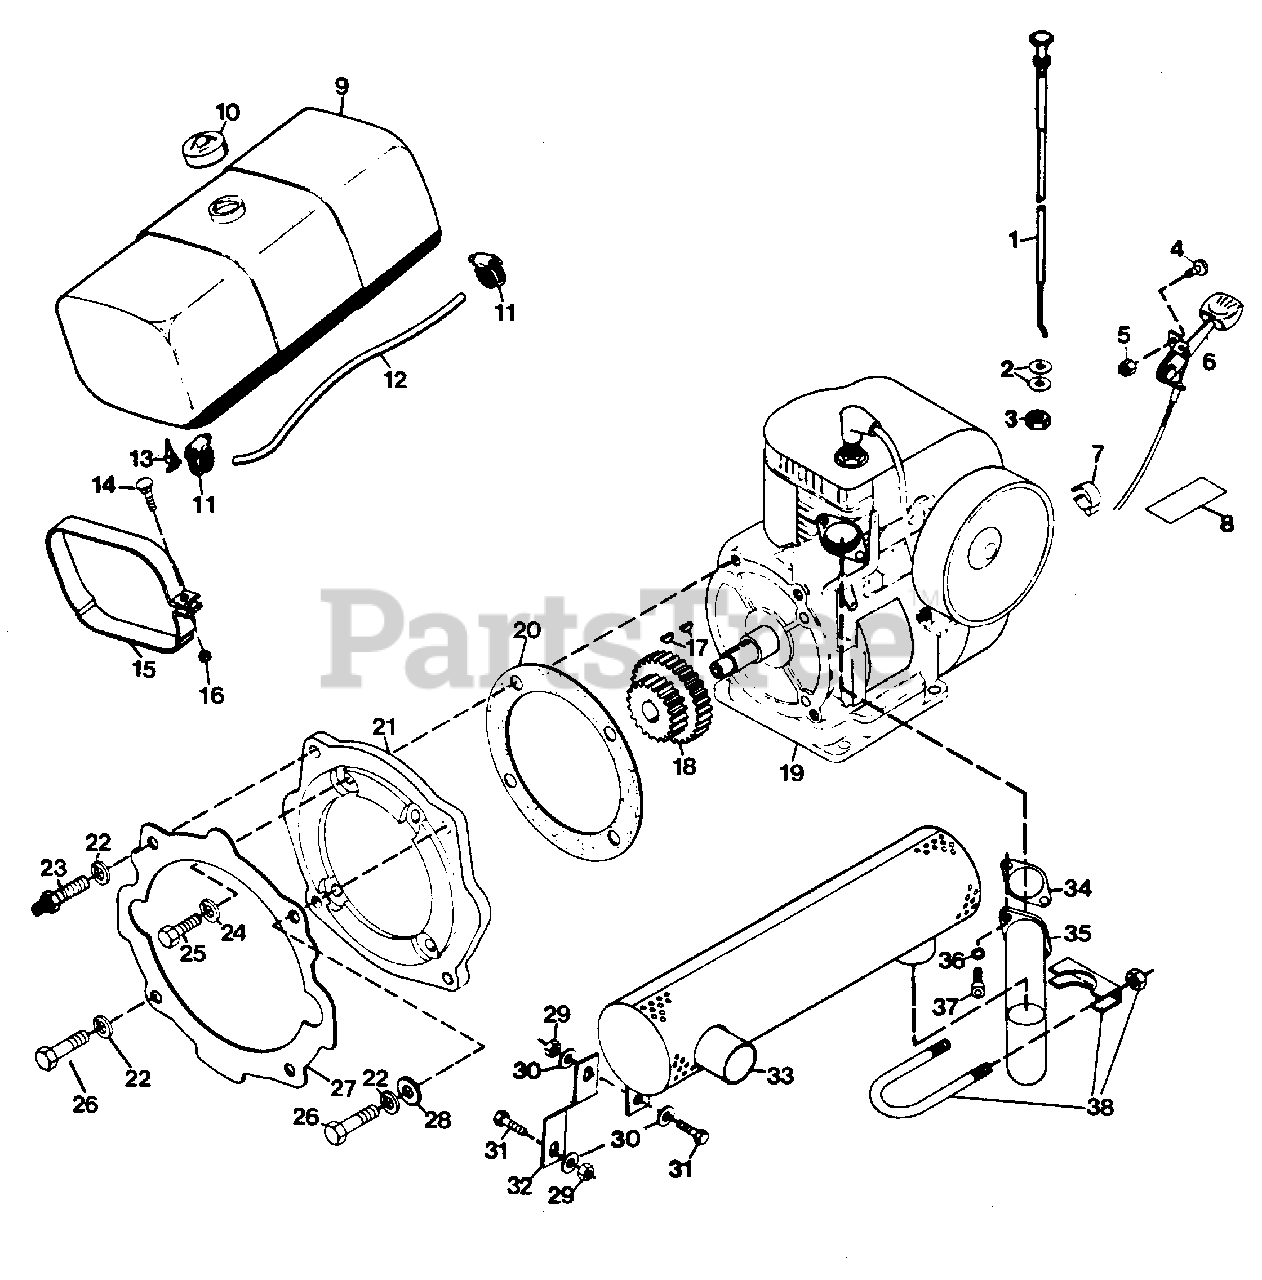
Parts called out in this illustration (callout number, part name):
1	LEVER, CHOKE CONTROL
2	WASHER, FLAT .406X.812X.065
3	NUT, HEX JAM 3/8-24
4	SCREW, MACH. 10-24X.50 PHD
5	NUT, LOCK 10-24
6	LEVER, THROTTLE CONTROL
7	CLIP, CONDUIT
8	DECAL, THROTTLE
9	ASSEMBLY, FUEL TANK
10	CAP, GAS TANK
11	CLAMP, HOSE
12	LINE, FUEL
13	VALVE AND STRAINER
14	BOLT, 1/4-20X1.75 RD.HD.SQ.NECK
15	STRAP, FUEL TANK
16	NUT, LOCK 1/4-20
17	KEY, WOODRUFF 5/32X5/8 HARD #6
18	GEAR, 10/12 DP 21/30 TEETH
19	ENGINE, 16 H.P.
20	GASKET, ENGINE TO ADAPTOR
21	ADAPTOR, ENGINE
22	WASHER, LOCK 7/16 SP HEAVY
23	STUD
24	WASHER, LOCK 3/8 SP HEAVY
25	BOLT, HEX 3/8-16X1
26	BOLT, HEX 7/16-14X1.25
27	GASKET, CHASSIS TO ADAPTOR
28	WASHER, FLAT .469X.938X.065
29	NUT, HEX 1/4-20
30	WASHER, FLAT .312X.734X.065
31	BOLT, HEX 1/4-20X.75
32	BRACE
33	MUFFLER
34	GASKET 16 H.P.
34	GASKET 12 H.P.
35	HEADER, EXHAUST 16 H.P.
35	HEADER, EXHAUST 12 H.P.
36	WASHER, LOCK 5/16 REG.
37	SCREW, CAP 5/16-18X.75 SHD
38	CLAMP, MUFFLER
